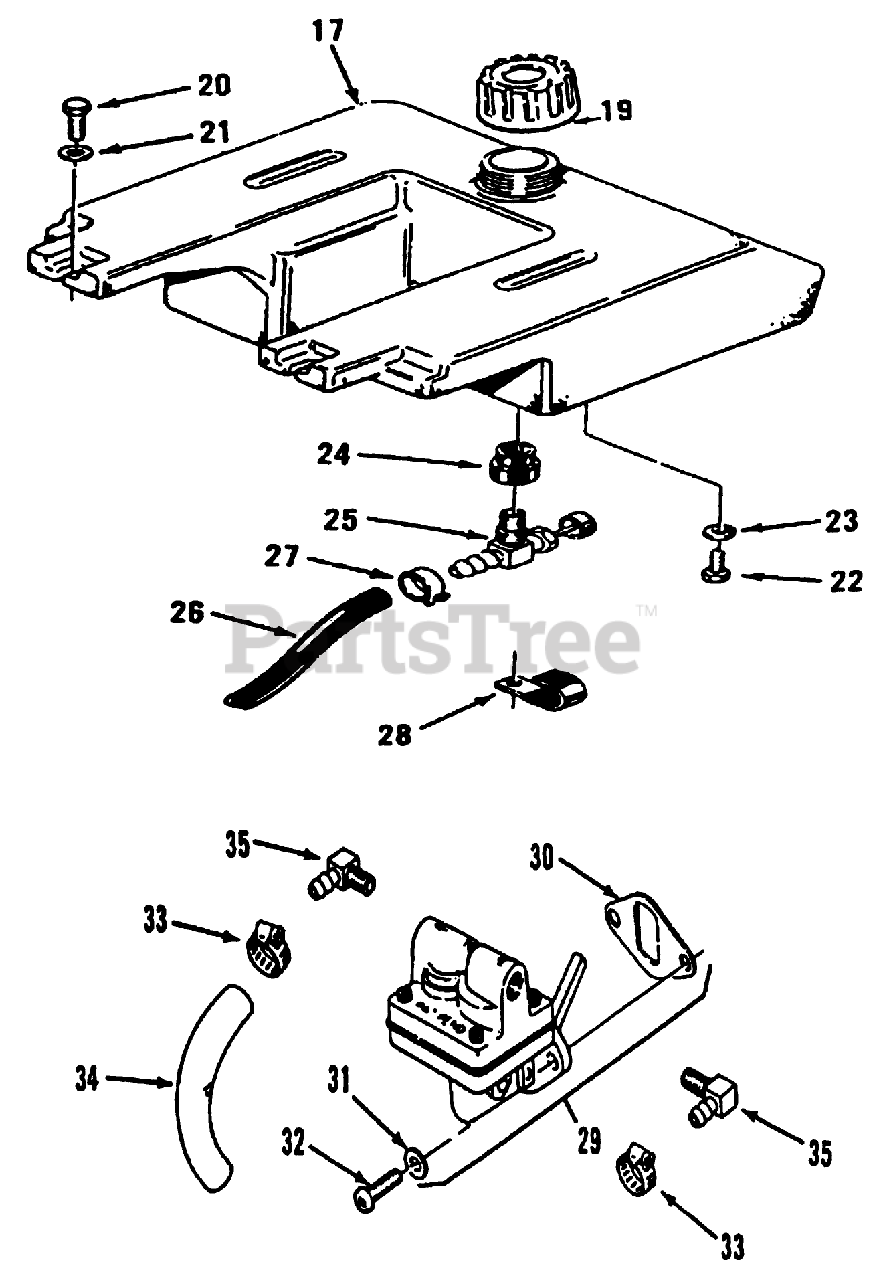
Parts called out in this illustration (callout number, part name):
17	TANK-FUEL
19	GAS CAP ASM
21	WASHER-FLAT
22	SCREW-HH
23	WASHER-LOCK
25	VALVE-FUEL
29	KOHLER 47-559-08
30	KOHLER 25-041-05
31	KOHLER X-25-63
32	KOHLER X-174-2
33	KOHLER X-426-9
34	KOHLER 25-353-01
35	KOHLER 25-155-02
